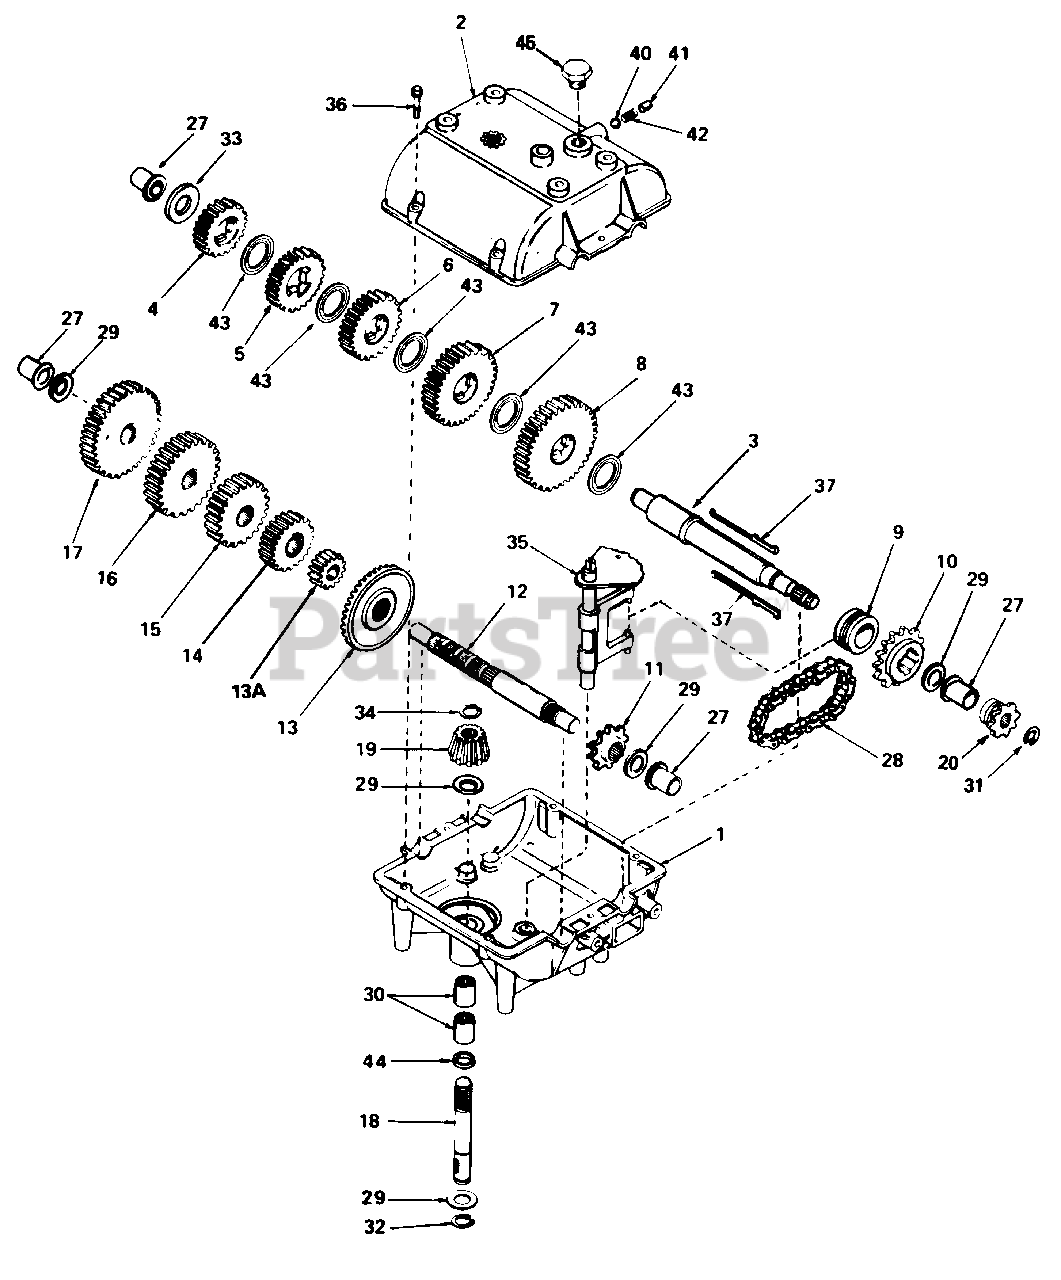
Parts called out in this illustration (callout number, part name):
1	CASE, Transmission
2	COVER, Transmission
3	SHAFT, Output
4	GEAR, Spur (20 teeth)
5	GEAR, Spur (22 teeth)
6	GEAR, Spur (25 teeth)
7	GEAR, Spur (30 teeth)
8	GEAR, Spur (35 teeth)
9	COLLAR, Shift
10	SPROCKET, (18 teeth)
11	SPROCKET, (9 teeth)
12	SHAFT, Counter
13	GEAR, Bevel (42 teeth)
13A	GEAR, Spur (15 teeth)
14	GEAR, Spur (20 teeth)
15	GEAR, Spur (25 teeth)
16	GEAR, Spur (28 teeth)
17	GEAR, Spur (30 teeth)
18	SHAFT, Input
19	BEVEL PINION, Input
20	SPROCKET (8 teeth)
27	BUSHING, Flanged
28	CHAIN, Roller (No. 41 chain, 24 links)
29	WASHER, Thrust
30	BEARING, Needle
31	RING, Retaining
32	RING, Retaining
34	RING, Retaining
35	ROD & FORK ASSY., Shift
36	SCREW, Flanged Hex Hd., Thread Forming, 1/4-20 x 1-1/4
40	BALL, Steel, 5/16"
41	SCREW, Set, 3/8-16 x 3/8
43	WASHER, Thrust
